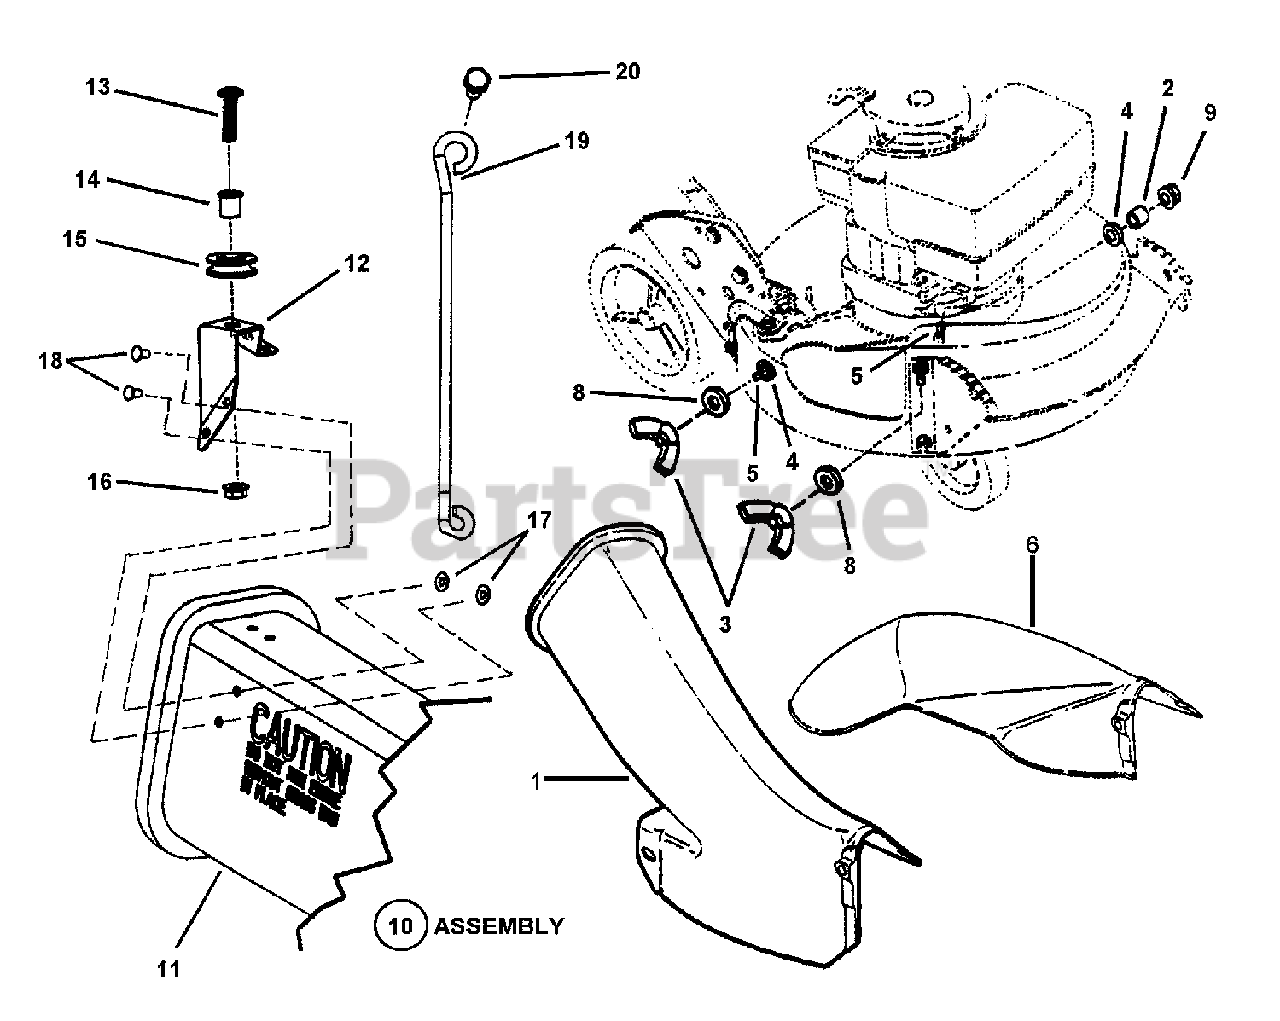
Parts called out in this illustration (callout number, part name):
1	ADAPTER, Grass Bag
2	SPACER
3	NUT, 5/16-18 Wing (Nylon Patch)
4	RETAINER, 5/16 Bolt
5	BOLT, 5/16-18 x 3/4" Short Neck Carriage, Grade 5
6	KIT, Side Chute
7	CHUTE, Side
8	WASHER, 5/16 Flat
9	NUT, 5/16-18 Hex Large Flange Center Lock
10	ASSEMBLY, Bag Adapter
11	ADAPTER, Bag
12	BRACKET, Rope Pulley
13	SCREW, 5/16 - 18 x 1-1/4" Pan Head Machine
14	BUSHING, Flange
15	PULLEY, Plastic
16	NUT, 5/16 - 18 Hex Flange Lock, Grade 5
17	WASHER, 15/32"
18	RIVET, 3/16 x .344
19	BRACE, Bag Adapter
20	SCREW, M6 1.0X12MM, Hex Head, CZ
